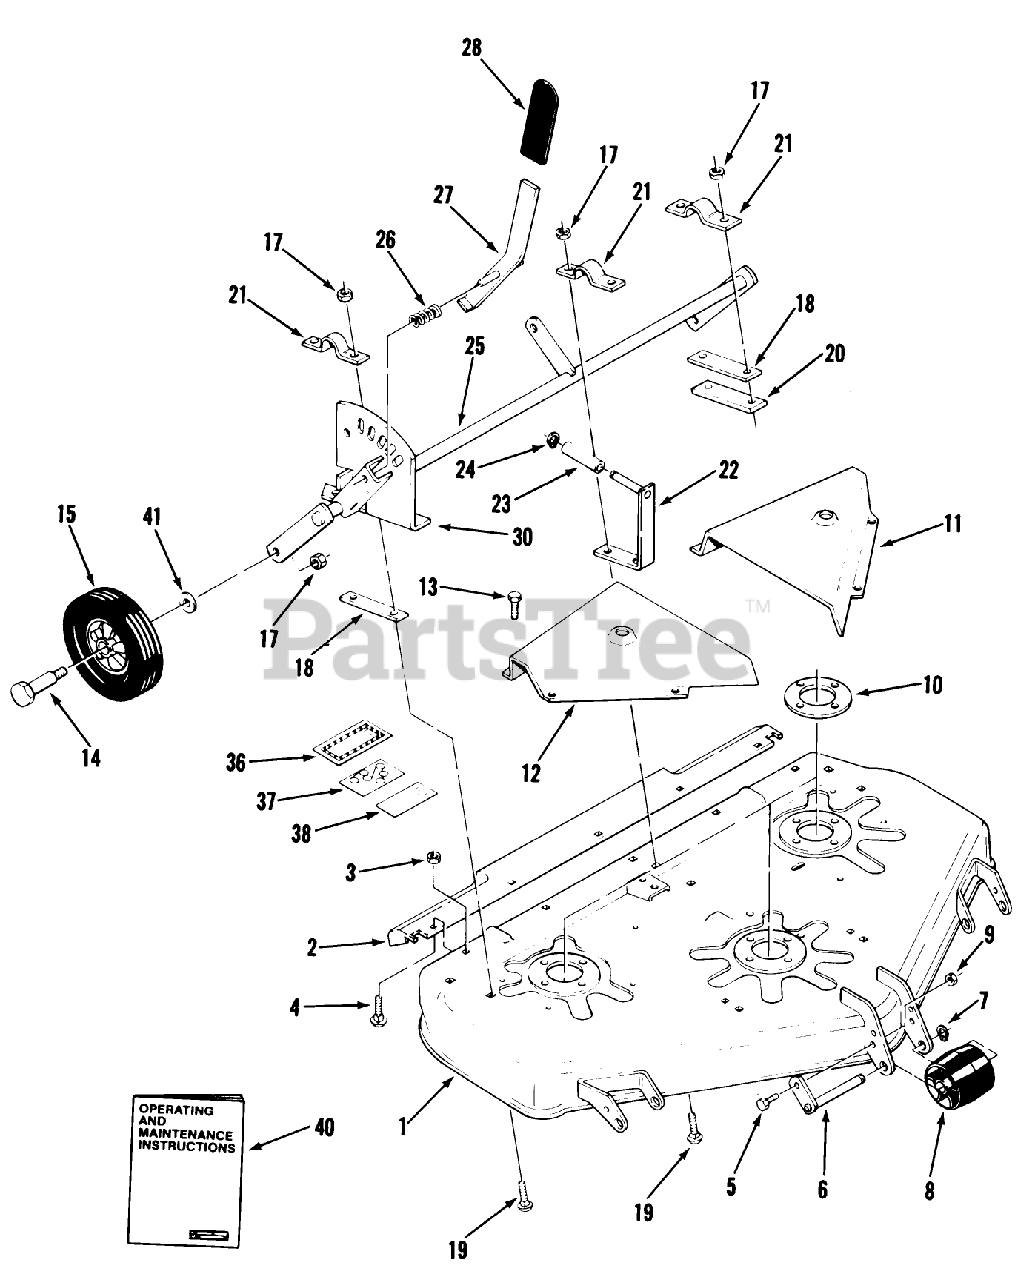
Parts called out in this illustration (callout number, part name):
4	CARRIAGE BOLT -4
10	PLATE-SPINDLE
13	Bolt
14	BOLT-SHOULDER
26	SPRING-COMPRESSION
29	HANDLE-EXTENSION *R
37	DECAL-HEIGHT BELT
40	Operating and Maintenance Instructions
41	WASHER-FLAT
